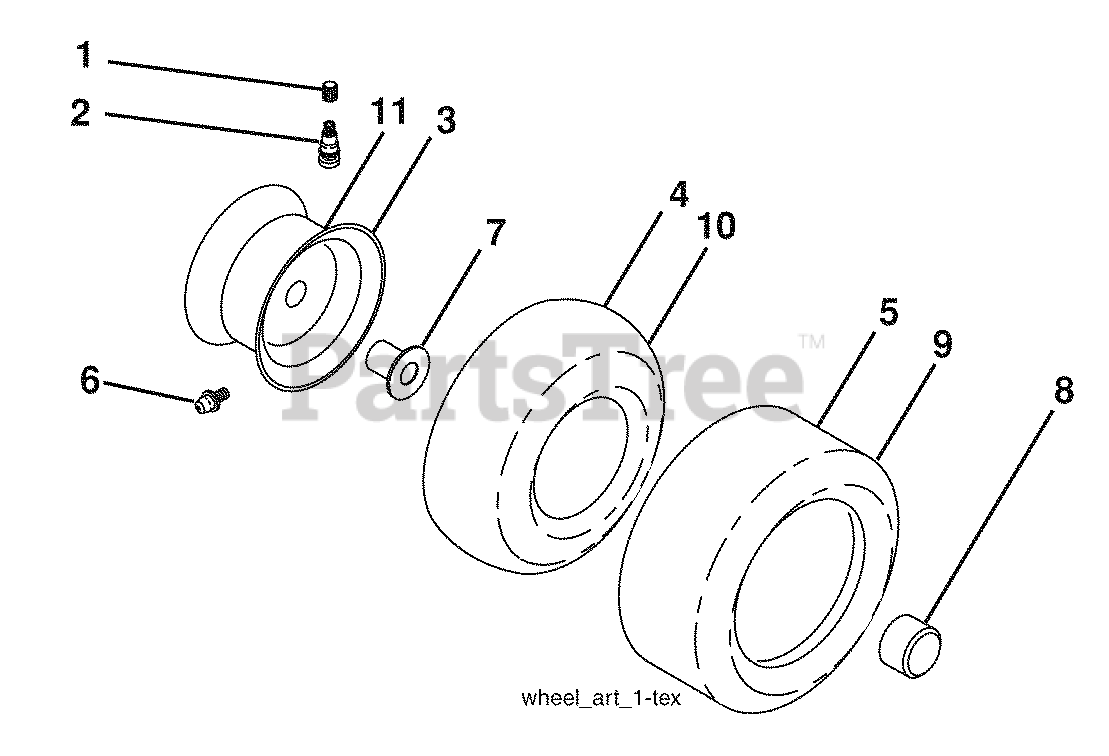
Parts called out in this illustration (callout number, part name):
1	Cap Valve Tire
2	Stem Valve
3	Rim Front
4	Tube Front
5	Tire Front 15 x 6.0-6
6	Fitting Grease
7	Bearing Flange
8	Cap Axle Blk 1 50 x 1 00
9	Tire R 18 x 9.5-8 Turf Saver LT
10	Tube Rear
11	Rim Asm 8" Rear
